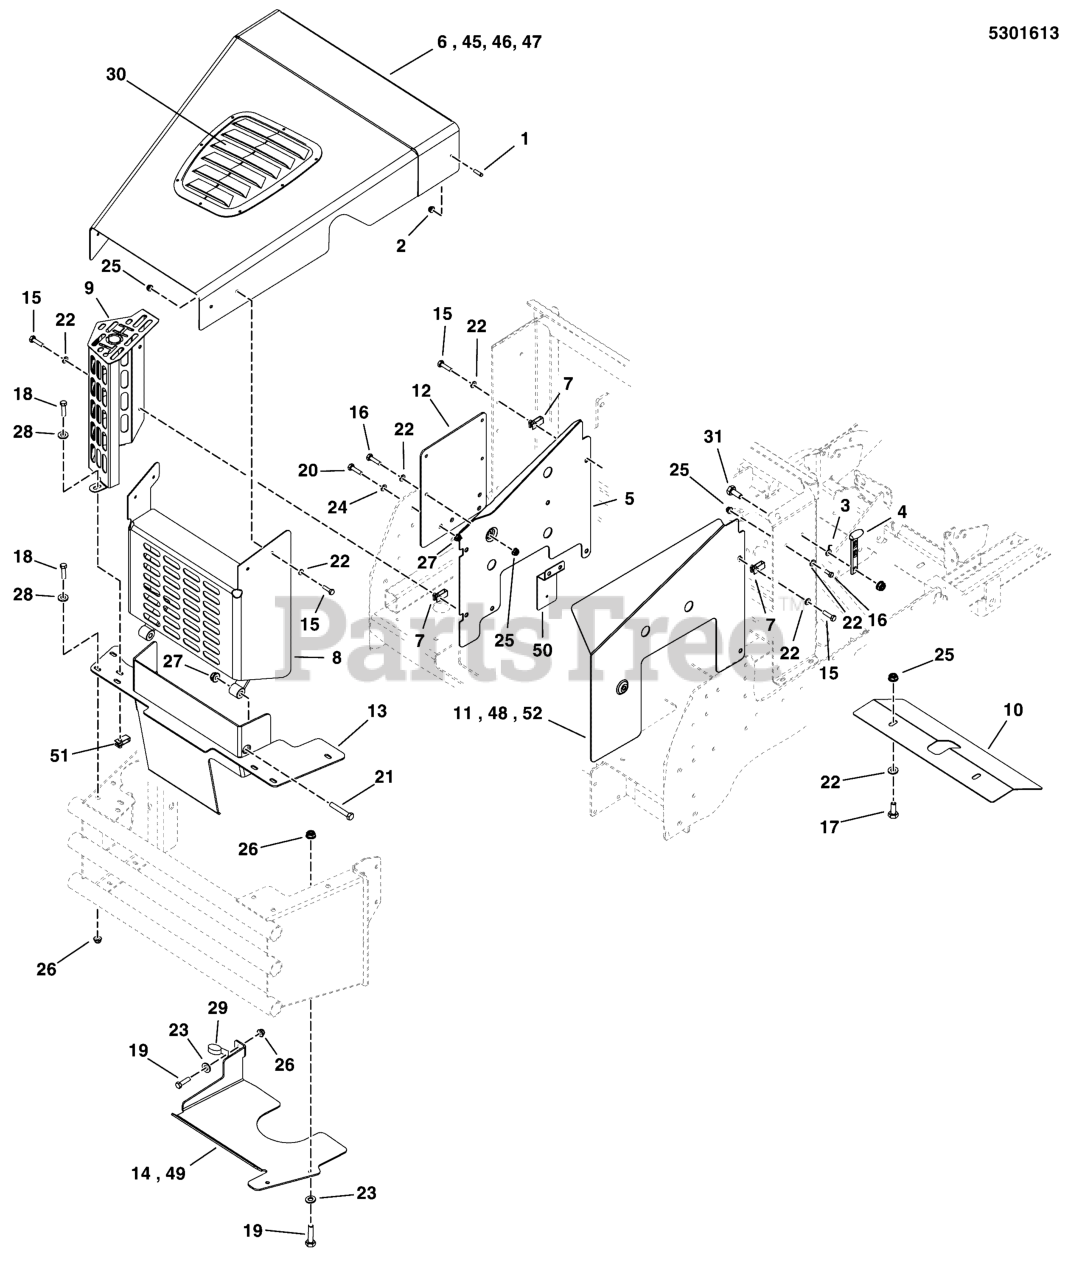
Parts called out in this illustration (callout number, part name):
1	BINDING POST #8-32X.500 INT THR BLK
2	SCREW-HEX SERR FLNG LK # 8-32X0.375 YEL
3	HOOK-.125DIA WIRE GR CAT STRAP YELLOW
4	STRAP,HOOD,BLACK RUBBER
5	SIDE PANEL, LH - RED
6	WELD, HOOD, IS2500 - RED
7	BODY CLIP, 1/4-20 X 1/2 DEEP
8	WELD, REAR COVER - RED
9	WELD, MUFFLER GUARD, 2500 - RED
10	PLATE, SHIELD, HYDRAULIC PUMPS - RED
11	COVER, SIDE, RH - RED
12	PLATE, HYDRAULIC TANK MOUNT - RED
13	WELD, GUARD, PTO BELT - RED
14	GUARD, DECK BELT, IS2500Z
15	BOLT, 1/4-20 X 3/4 GD5 YZ
16	BOLT, 1/4-20 X 1" GD5 CZ
17	BOLT, 1/4-20 X 1-1/4, GD5
18	BOLT, 5/16-18 X 3/4 GD5
19	BOLT, 5/16-18 X 1 GD5
20	BOLT, 3/8-16 X 1" GD5 CZ
21	BOLT, 3/8-16 X 2-1/4" GD5 CZ
22	WASHER, 1/4 SAE
23	WASHER, 5/16" SAE
24	WASHER, 3/8 SAE
25	NUT, 1/4-20 HEX NYLOCK FLANGE
26	NUT, 5/16-18 HEX NYLOCK FLANGE
27	NUT, 3/8-16 HEX NYLOCK FLANGE
28	WASHER, 5/16 GD.9 FLAT
29	CLAMP, HOSE, 1.000 DIA.
30	SCOOP, HOOD, OUTFRONT MOWER
31	BOLT,1/4-20X0.750,GR5,STD NECK,SQ,ZC/CL
45	WELD, HOOD, IS2500 - RED
46	WELD, HOOD, IS2500 - RED
47	WELD, HOOD, IS2500 - RED
48	COVER, SIDE, RH - RED
49	GUARD, DECK BELT
50	MOUNT, MAXI FUSE
51	BODY CLIP, 5/16-18, 1/4 MATERIAL
52	COVER, SIDE, RH
